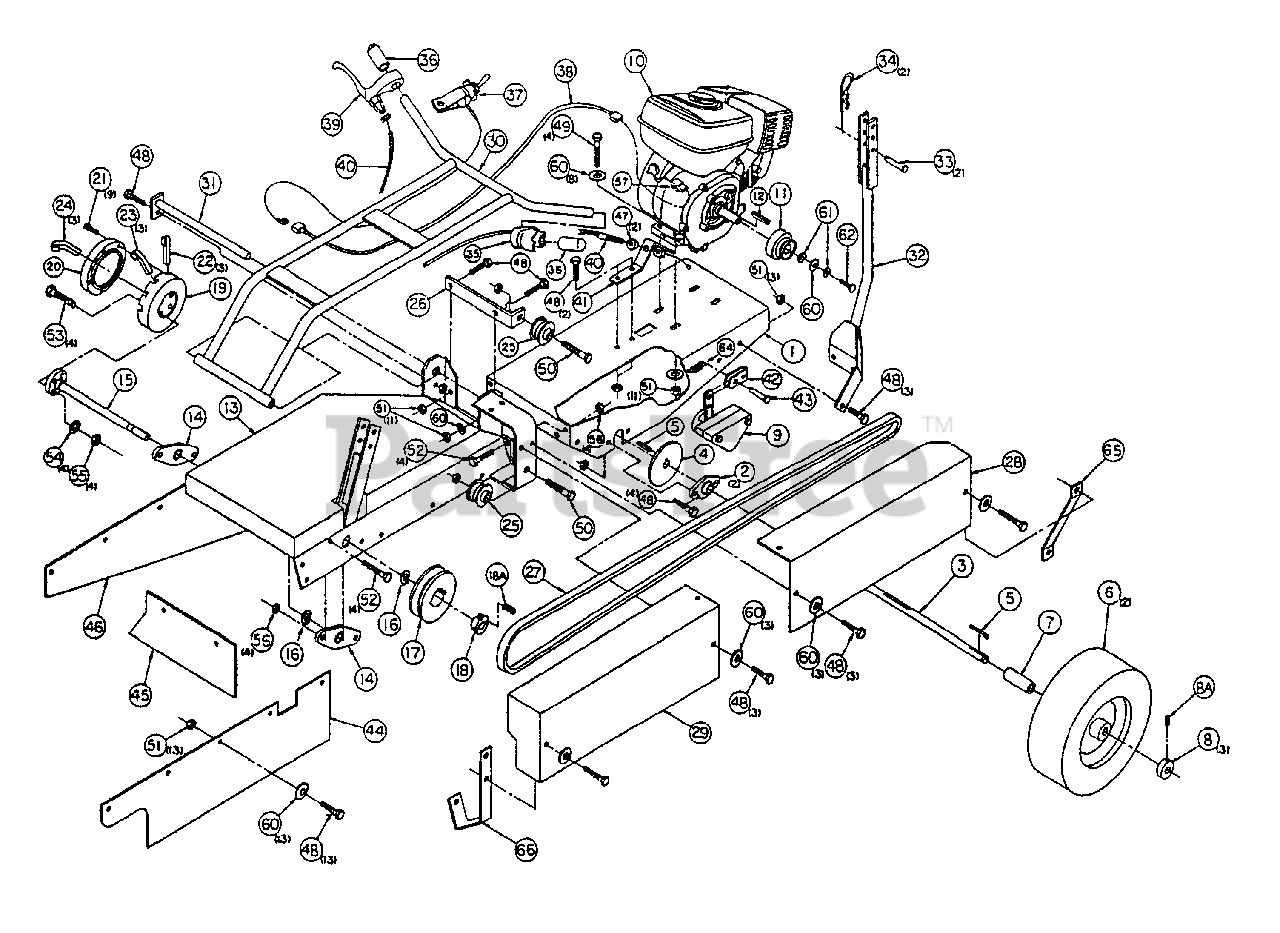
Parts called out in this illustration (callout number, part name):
1	Engine Base Weldment
2	Bearing w/ 1" Dia. Bore
4	Brake Rotor
5	1/4" x 1/4" x 2" Key
6	Wheel (13 x 5.00-6)
7	Wheel Spacer
8	Axle Locking Collar
8A	5/16-18 x 5/16" Set Screw
9	Brake Caliper
10	* Engine Briggs & Stratton
11	Clutch - 3/4 Ball Bearing
12	3/16 x 3/16" x 1" Shaft Key
13	Head Frame Weldment
14	Bearing 1-3/16" Bore
15	Drive Shaft Weldment
16	1-3/16" Retaining Ring
17	Pulley - 5 3/4 Dia.
18	Bushing 1 3/16"
18A	3/8-16" x 5/8" Lg. Set Screw
19	Cutter Head Body
20	Cutter Head Cover
21	3/8-24 x 1" Socket Hd. Cap Screw GR8
22	Cutter Teeth - Straight
23	Cutter Teeth - 25 Degree
24	Cutter Teeth - 45 Degree
25	Idler Pulley
26	Idler Arm
27	Belt - Kevlar
28	Belt Guard - Engine
29	Belt Guard - Head
30	Handle Weldment
31	Pivot Pin
32	Handle Bar Brace
33	Clevis Pin 5/16 x 2" Lg.
34	3/32" Hair Cotter
35	Throttle Cable Assembly
36	Black Handle Grip - 7/8" x 5"
37	Kill Switch - Toggle Type
38	Kill Switch Wire Assembly
39	Brake Handle
40	Brake Cable Assembly
41	Brake Cable Bracket
42	Full Clevis
43	Clevis Pin 1/4" x 7/8" Lg.
44	Drive Side Guard
45	Engine Side Guard
46	Open Side Guard
47	5/16-24 Jam Nut
48	5/16-18 x 1, HHCS
49	5/16-18 x 1-1/2" HHCS
50	5/16-18 x 2" HHCS
51	5/16-18 Nylok Locknut
52	3/8-16 x 1-1/4" HHCS
53	3/8-16 x 1-3/4" HHCS, GR5
54	3/8" Med. Split Lockwasher
55	3/8-16 Hex Nut
56	3/5-16 Nylok Locknut
57	Self-Stripping Wire Connector
60	5/16 Flatwasher
61	5/16 Med. Split Lockwasher
62	5/16-24 X 1-1/2 HHCS
65	Belt Guard Bracket - Engine
66	Belt Guard Bracket - Head
